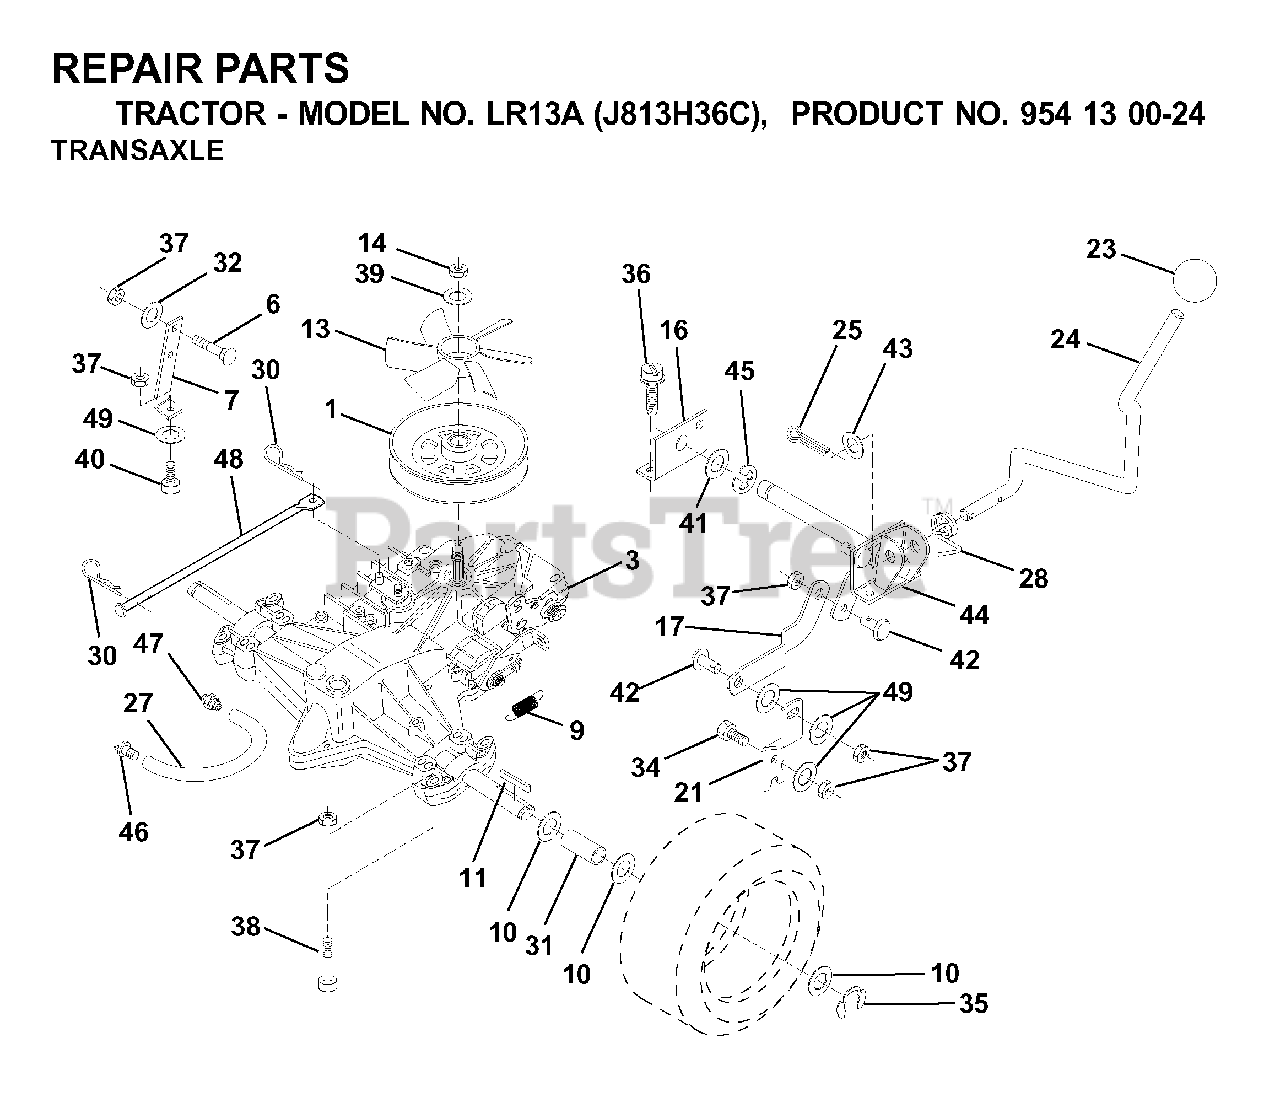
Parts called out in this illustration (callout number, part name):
3	TRANSAXLE HYDRO
6	BOLT
9	SPRING,BRAKE RETURN
11	SQUARE KEY
13	FAN.TRANSMISSION.HYDRO.6"
16	SUPPORT, SHIFT HANDLE
17	LINK, SHIFT
21	LEVER, SHIFT
23	PISTOL KNOB
24	ROD, SHIFTER
25	PIN COTTER
27	FUEL LINE
28	SPRING, TORSION
30	RETAINER M
31	SPACER SPLIT
32	WASHER
34	BOLT RB
35	E-RING LT
36	SCREW
37	NUT.71038.31-18.HEX.NYLOCK
40	BOLT
43	WASHER
44	PIVOT SHAFT
45	RETAINING RING LT
46	CAP, VENT ASSY
47	O-RING.ASM.70110
48	ACTUACTOR
49	WASHER M
